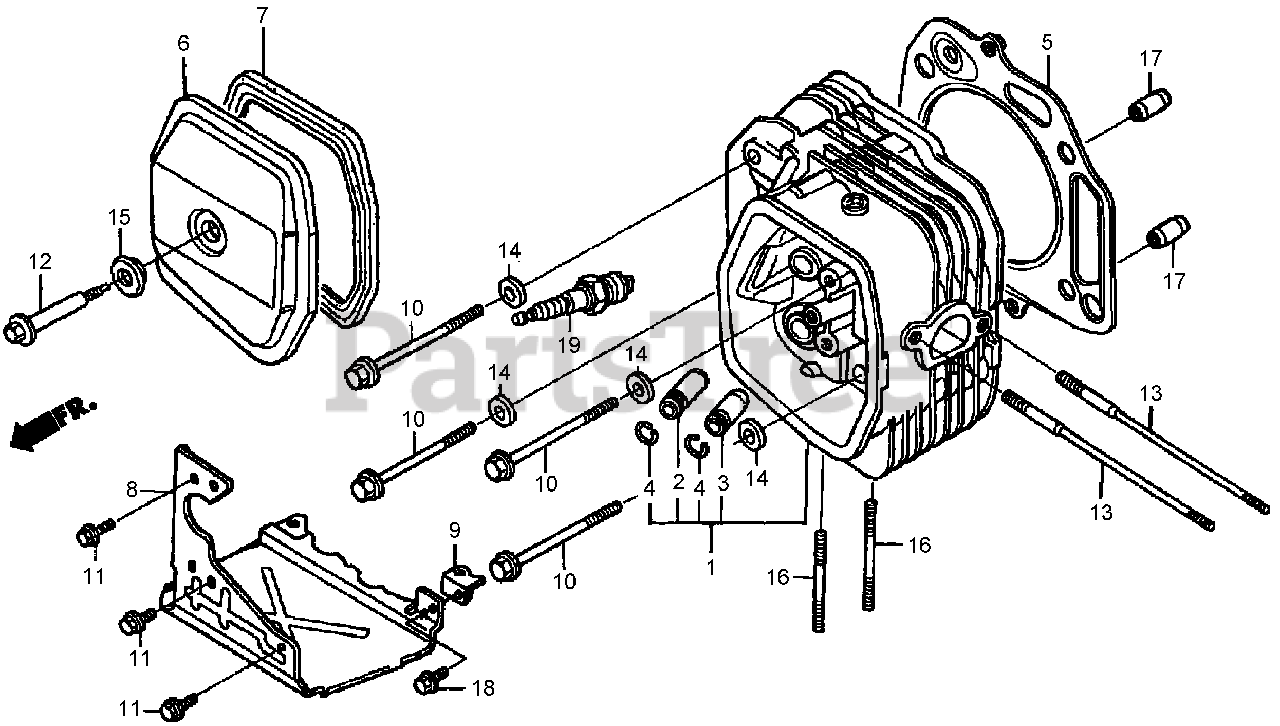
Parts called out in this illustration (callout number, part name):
1	HEAD-CYLINDER
2	GUIDE-VALVE
3	GUIDE-VALVE, EXHAUST
4	CLIP-GUIDE, VALVE
5	GASKET-HEAD, CYLINDER
6	COVER-HEAD
7	GASKET-HEAD COVER, CYLINDER
8	COVER (LOWER)
9	STAY-COVER (LOWER)
10	BOLT-FLANGE (10X85)
11	BOLT-FLANGE (6X12) (C T200)
12	BOLT-COVER, HEAD
13	BOLT-STUD
14	WASHER-PLAIN (10MM)
15	WASHER-HEAD COVER
16	BOLT-STUD (8X32)
17	PIN A-DOWEL
18	BOLT-FLANGE (6X12)
19	SPARK PLUG (B P R 5E S) (N G K)
